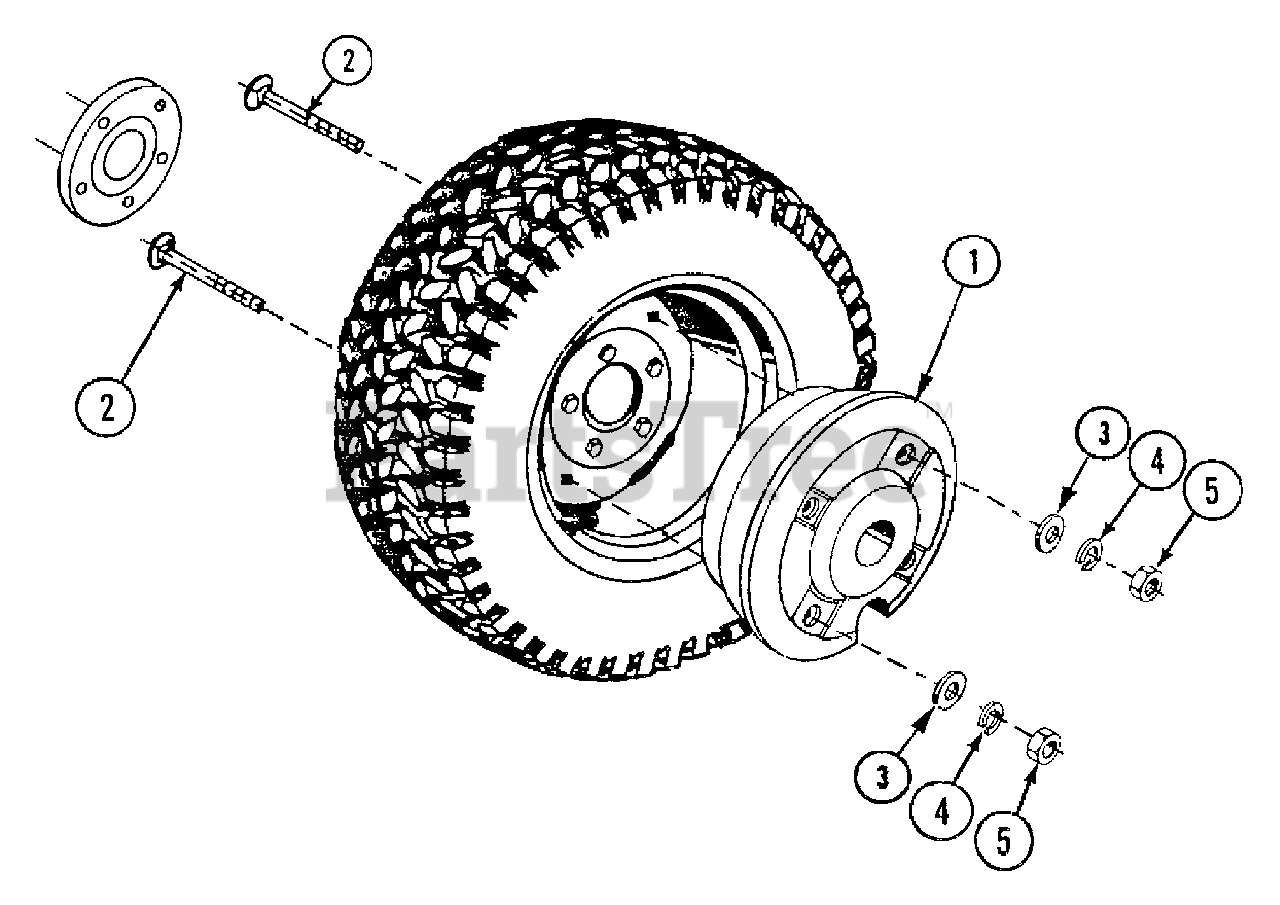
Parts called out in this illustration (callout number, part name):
1	Wheel Weight - 75 lb.
2	Carriage Bolt 1/2-13 x 8-1/2"
3	Flat Washer 1/2"
4	Lockwasher 1/2"
5	Nut 1/2"- 13
